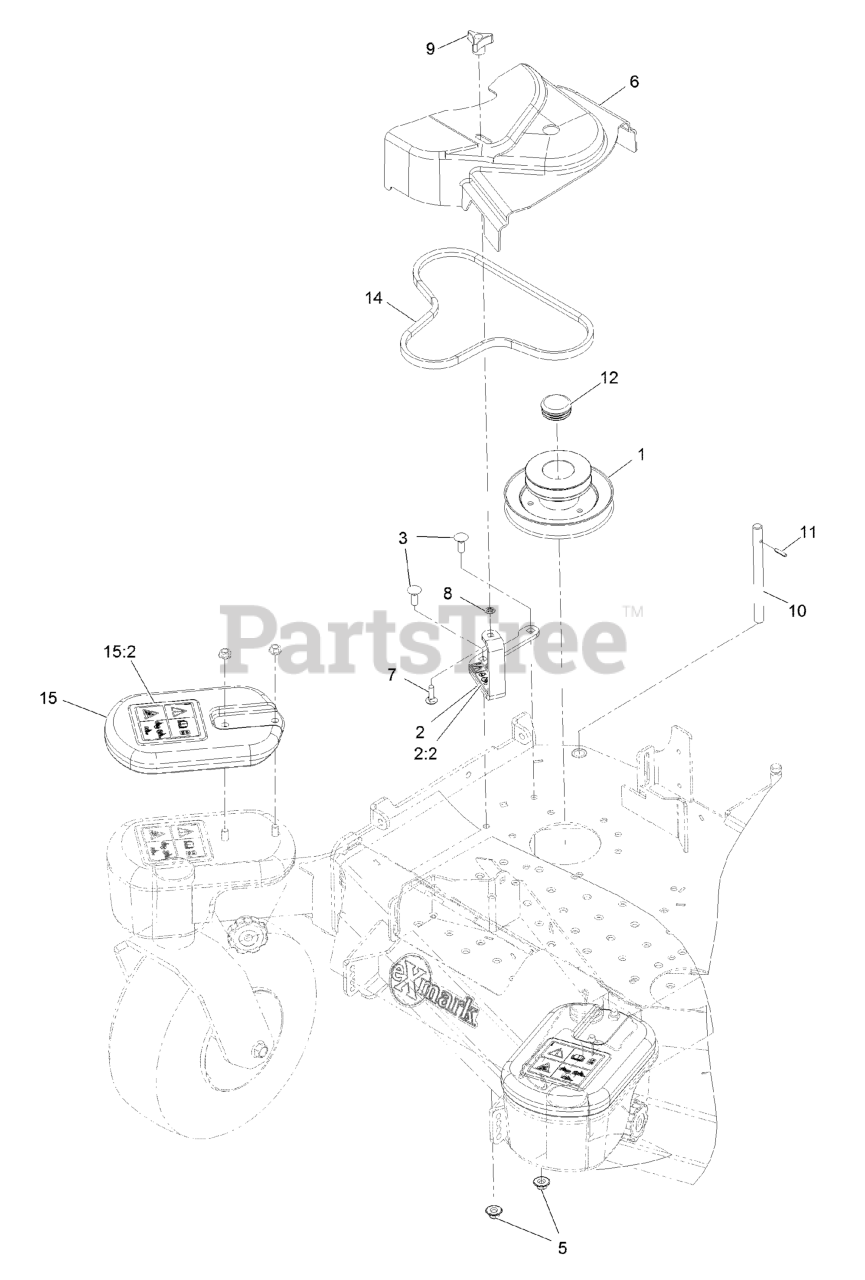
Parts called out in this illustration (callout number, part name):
1	JACKSHAFT- UV DRIVE 483
2	ASM-CVR BRKT W/DECAL
2:2	DECAL-DANGER
3	BOLT-CARR
5	Nut-Nyloc 3/8-16 Flg
6	COVER-BELT, UV 48
7	BOLT-CARR
8	RING-RETAINING, BOLT
9	KNOB-3 PRONG
10	SHAFT-CATCHER, GRASS
11	PIN-ROLL
12	PLUG-ROUND PLASTIC
14	BELT-BLOWER
15:2	DECAL-WARNING, TRACTION
